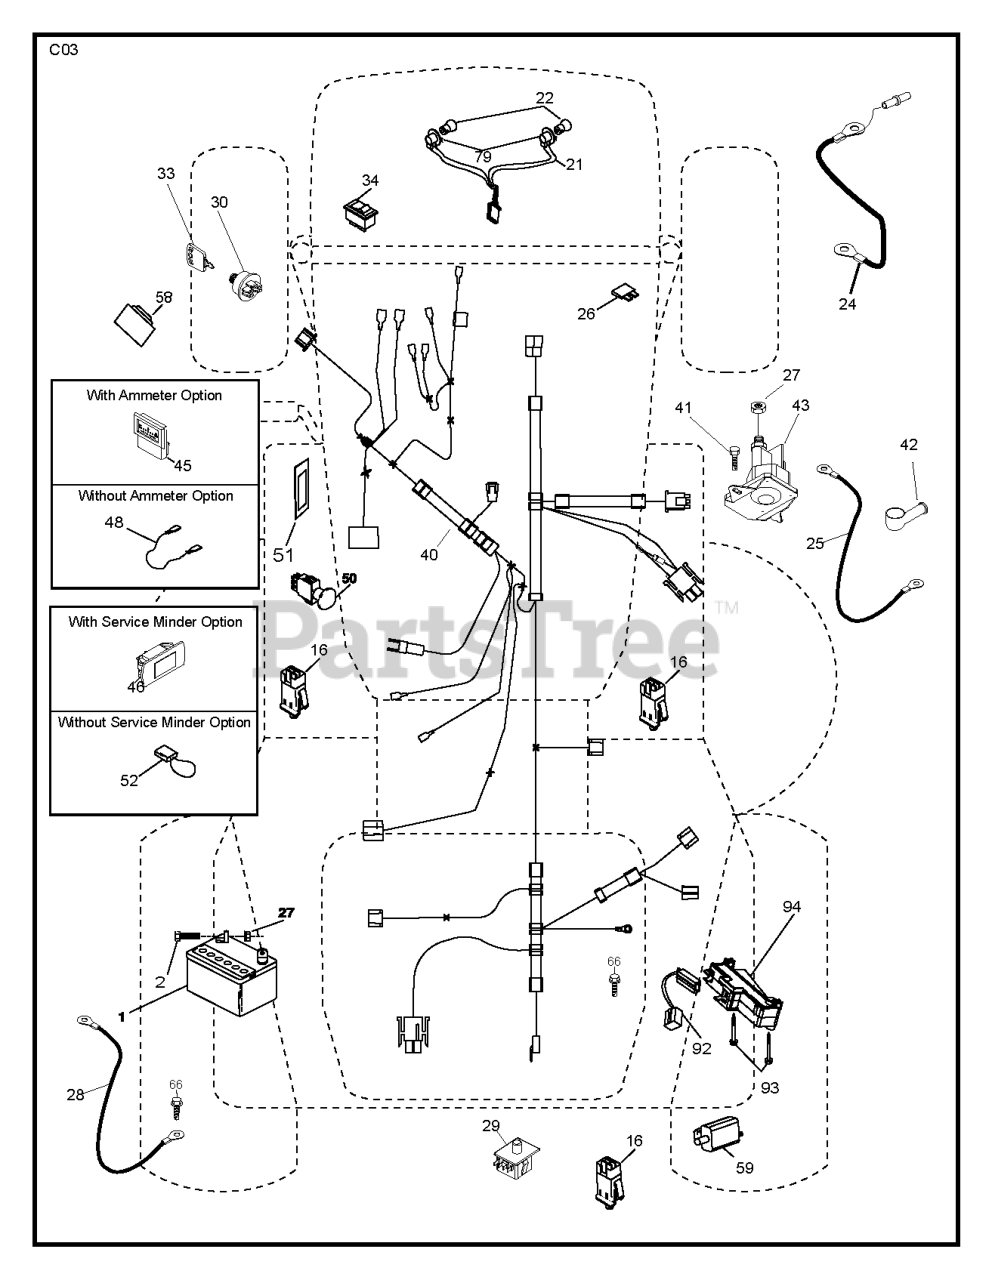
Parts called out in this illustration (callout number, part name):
1	Battery, Dry 30 Amp
2	BOLT.HEX.1/4.X.3/4.DICHROMATE
16	SWITCH INTERLOOK PUSH-IN
21	HARNESS.W/LIGHT SOCKET
24	CABLE BATTERY
25	CABLE.STARTER.6GA.11"RED
26	FUSE 20AMP
27	NUT
28	CABLE GROUND
29	SWITCH.SEAT.DP W/RAMPS
30	SWITCH.IGN.DELTA.W.LGH.ROS
33	KEY.CHAIN.BLISTER.PACK.GEN.INT
40	RP HARNESS.IGN.ELECT.REG.CRD
41	BOLT
42	TERMINAL COVER
43	SOLENOID.W/BRASS.PLUNGER
48	ADAPTER.AMMETER
50	RP.PTO.SWITCH.8 TERMINAL.BLACK
51	FRAME RETAINING RING
52	WIRE PROTECTION LOOP
58	BUZZER
59	.WITCH.FULL BAGGER.INDICATOR
66	SCREW LT
79	BULB HOLDER ASM.
92	HARNESS.PIGTAIL.CONSLE
93	SCREW.PLASTITE
94	MODULE.REVERSE.ROS
